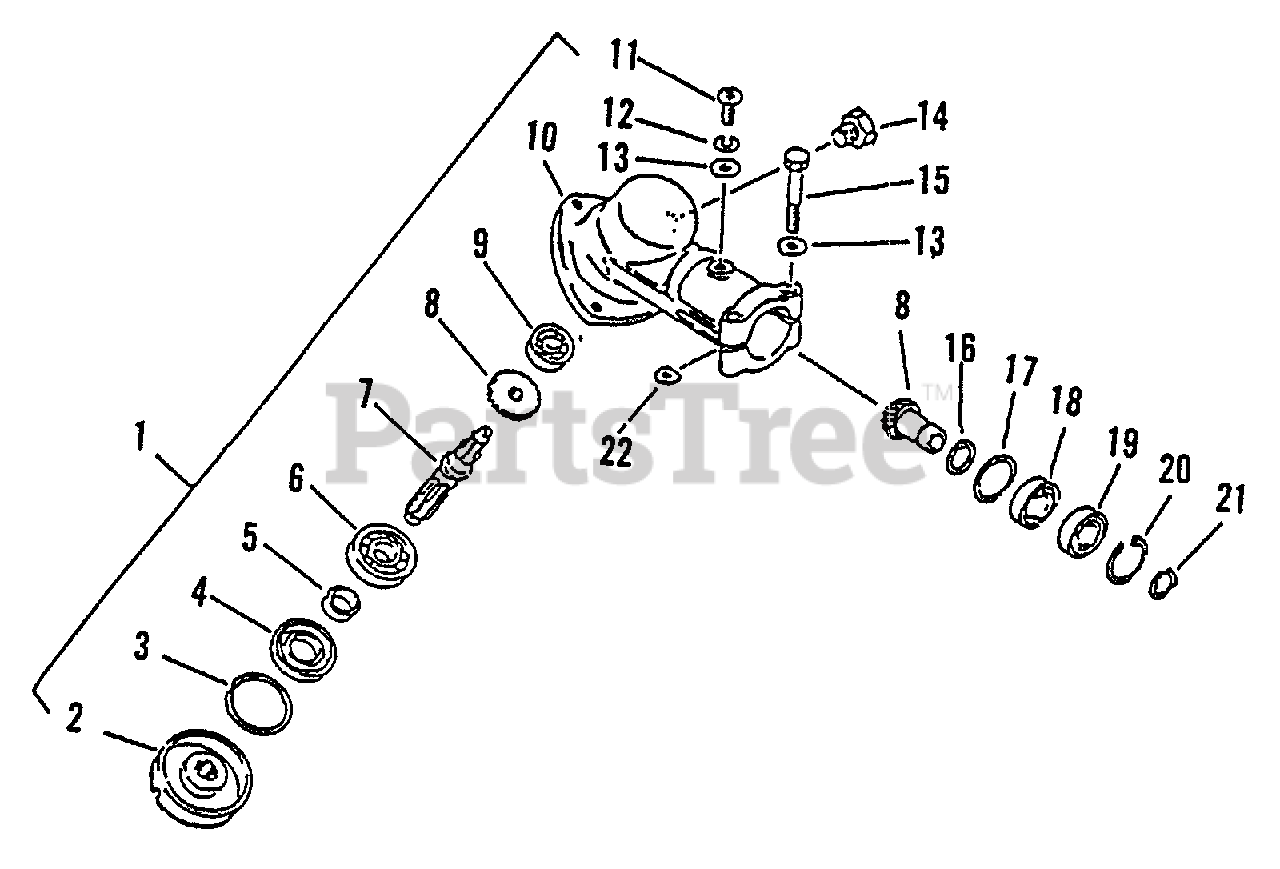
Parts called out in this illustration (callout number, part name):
1	Housing Ast, Gear
2	Plate, Adapter (U)
3	Circlip 32
6	Bearing, Ball 6201
7	Shaft, P.T.O
8	Gear set, Bevel
9	Bearing, Ball 609
10	Housing, Gear
11	Screw 5x10
12	Washer, Spring 5
13	Washer 5
14	Bolt 8x8
15	Bolt 5x35
16	Washer, Adjustment
17	Washer, Adjustment
18	Bearing, Ball 6900
19	Bearing, Ball 6900
20	Circlip 22
21	Circlip 12
22	Washer, Shim
